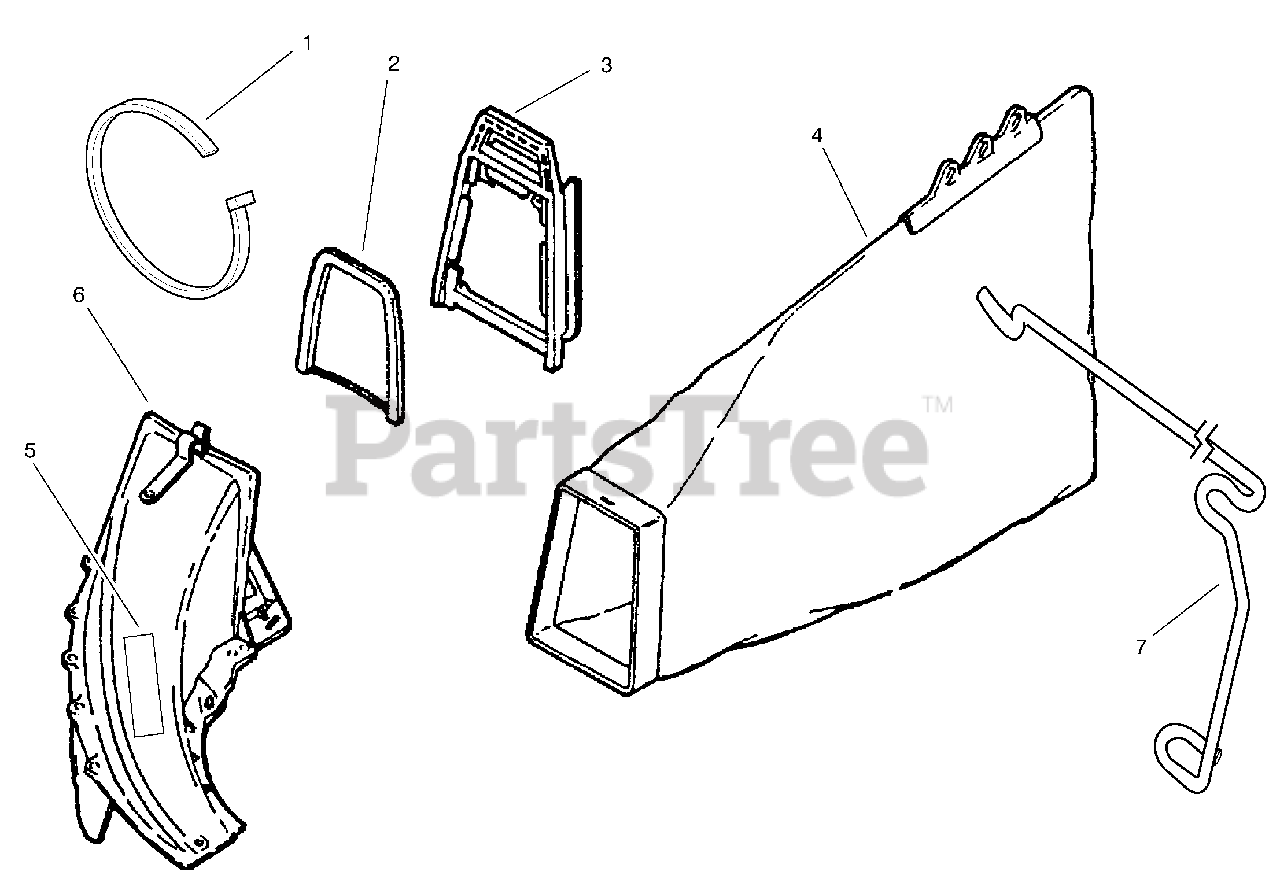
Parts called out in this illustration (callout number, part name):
1	Strap-Tie
2	Brace-Chute
3	Adaptor-Chute
4	Bag-Grass
5	Decal-Danger
6	Chute Assembly
7	Rod-Grass Bag
